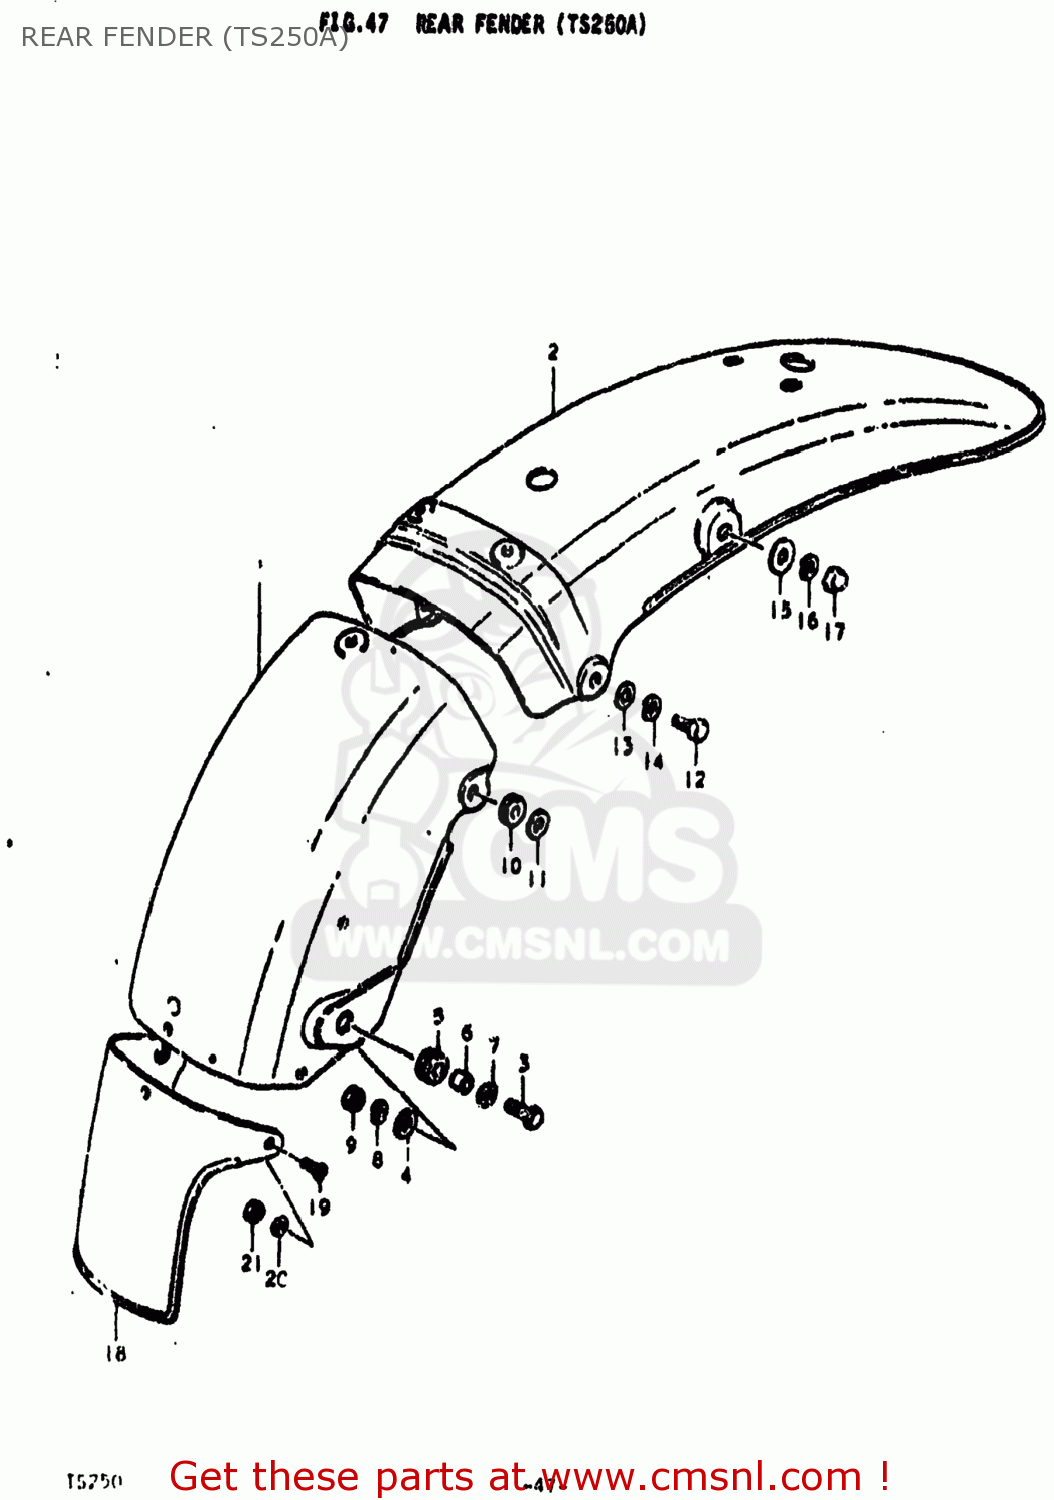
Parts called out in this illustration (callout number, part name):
1	FENDER,REAR
2	FENDER,REAR
3	BOLT
4	WASHER (6.5X20X1.2)
5	CUSHION
6	SPACER(6.1X9X7.5)
7	WASHER
8	LOCK WASHER
9	NUT
10	CUSHION
11	WASHER
12	BOLT
13	WASHER 6MM
14	LOCK WASHER
15	WASHER(10.3X25X1.5
16	LOCK WASHER
17	NUT
18	MUD GUARD,REAR FENDER
19	SCREW
20	WASHER
21	NUT
